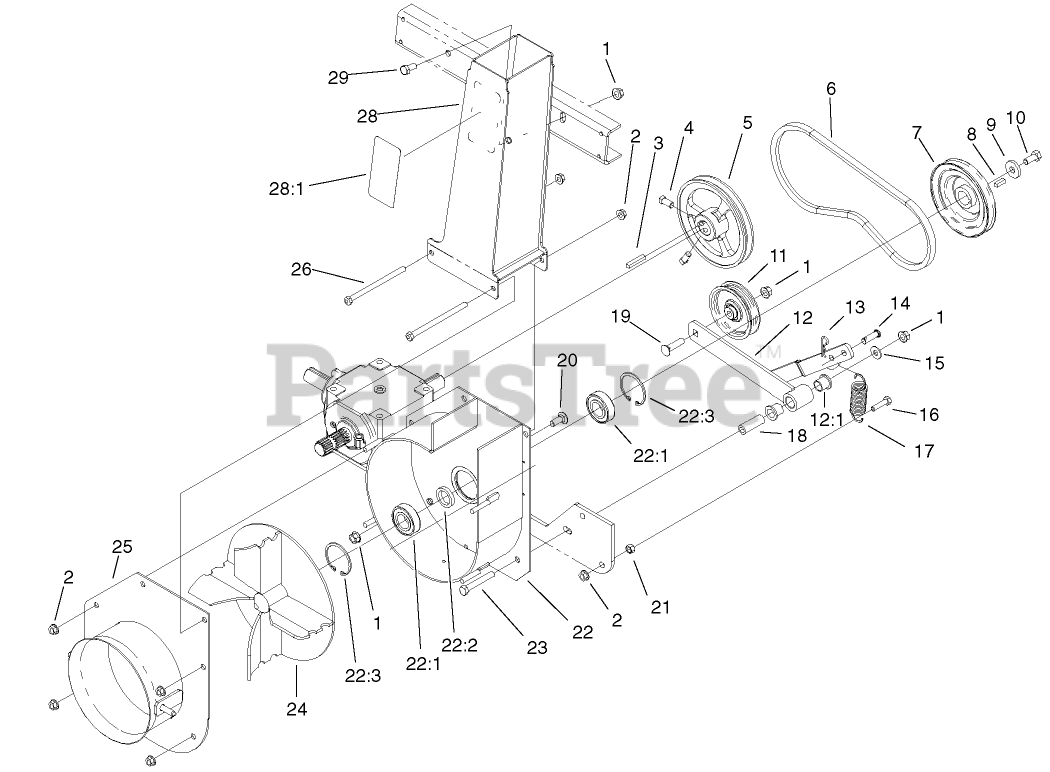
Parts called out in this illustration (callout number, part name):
1	NUT-HF
2	NUT-HF
3	KEY-SQUARE
4	SCREW-SET, SQH
5	PULLEY-GEARBOX
6	V-BELT
7	Pulley-Impeller
8	KEY-SQUARE
9	WASHER-THRUST, PLAIN
10	SCREW-HH
11	PULLEY-IDLER
12	IDLER ARM ASM
12:1	BUSHING-FLANGE
13	PIN-HAIR
14	PIN-CLEVIS
15	WASHER-FLAT
16	SCREW-HH
17	SPRING-EXTENSION
18	SPACER
19	SCREW-CARR
20	BOLT-CARR
21	NUT-HEX
22	BLOWER HOUSING ASM
22:1	BEARING-BALL
22:2	SPACER-BEARING
22:3	RING-SNAP
23	SCREW-HH
24	IMPELLER ASM
25	COVER ASM
26	SCREW-HH
28	IMPELLER CHUTE ASM
28:1	DECAL-DANGER
29	SCREW-HH
